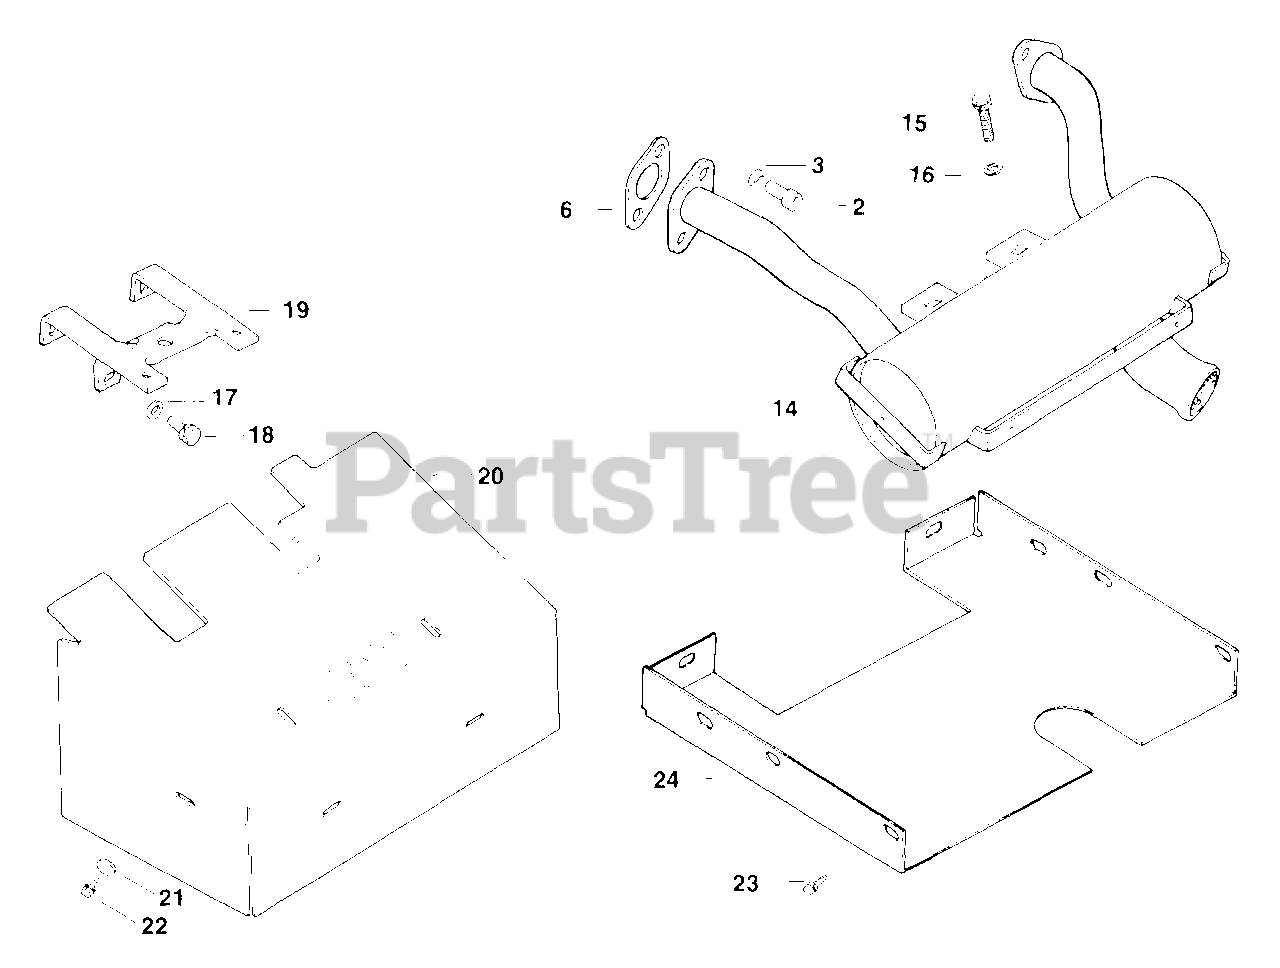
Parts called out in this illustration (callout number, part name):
2	SCREW, HEX SOCKET HEAD CAP USE 25 086 87-S
3	WASHER, SPRING LOCK 5/16"
14	MUFFLER - DISCONTINUED
17	WASHER, FLAT 1/4"
18	SCREW, WSH HD TAP 1/4-20-5/8" - DISCONTINUED
20	DUCT - USE 52 281 32
22	SCREW - USE 25 086 40
